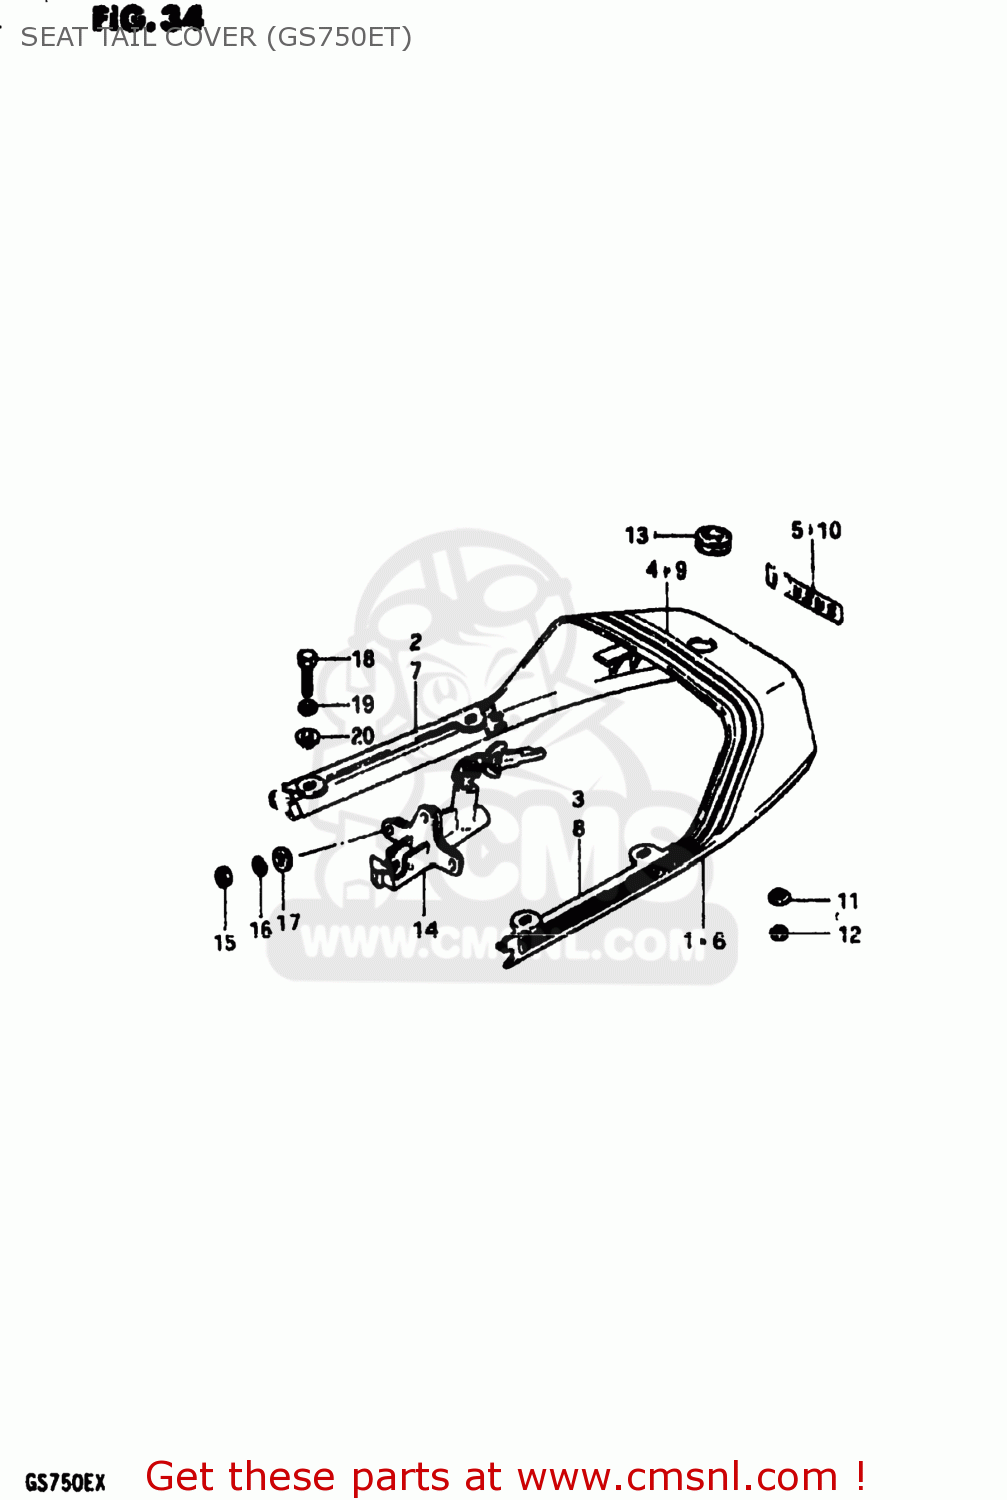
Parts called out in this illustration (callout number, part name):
1	COVER SET,SEAT TAIL
2	MOLDING,SEAT
3	MOLDING,SEAT
5	EMBLEM,SEAT TAIL COVER
6	COVER SET,SEAT TAIL
7	MOLDING,SEAT
8	MOLDING,SEAT
9	TAPE SET
10	EMBLEM (GOLD/BLACK)
11	WASHER
12	NUT 6MM
13	GROMMET,SEAT LOCK HOLE
14	LOCK SET
15	NUT 6MM
16	LOCK WASHER
17	WASHER 6MM
18	BOLT
19	LOCK WASHER
20	WASHER
